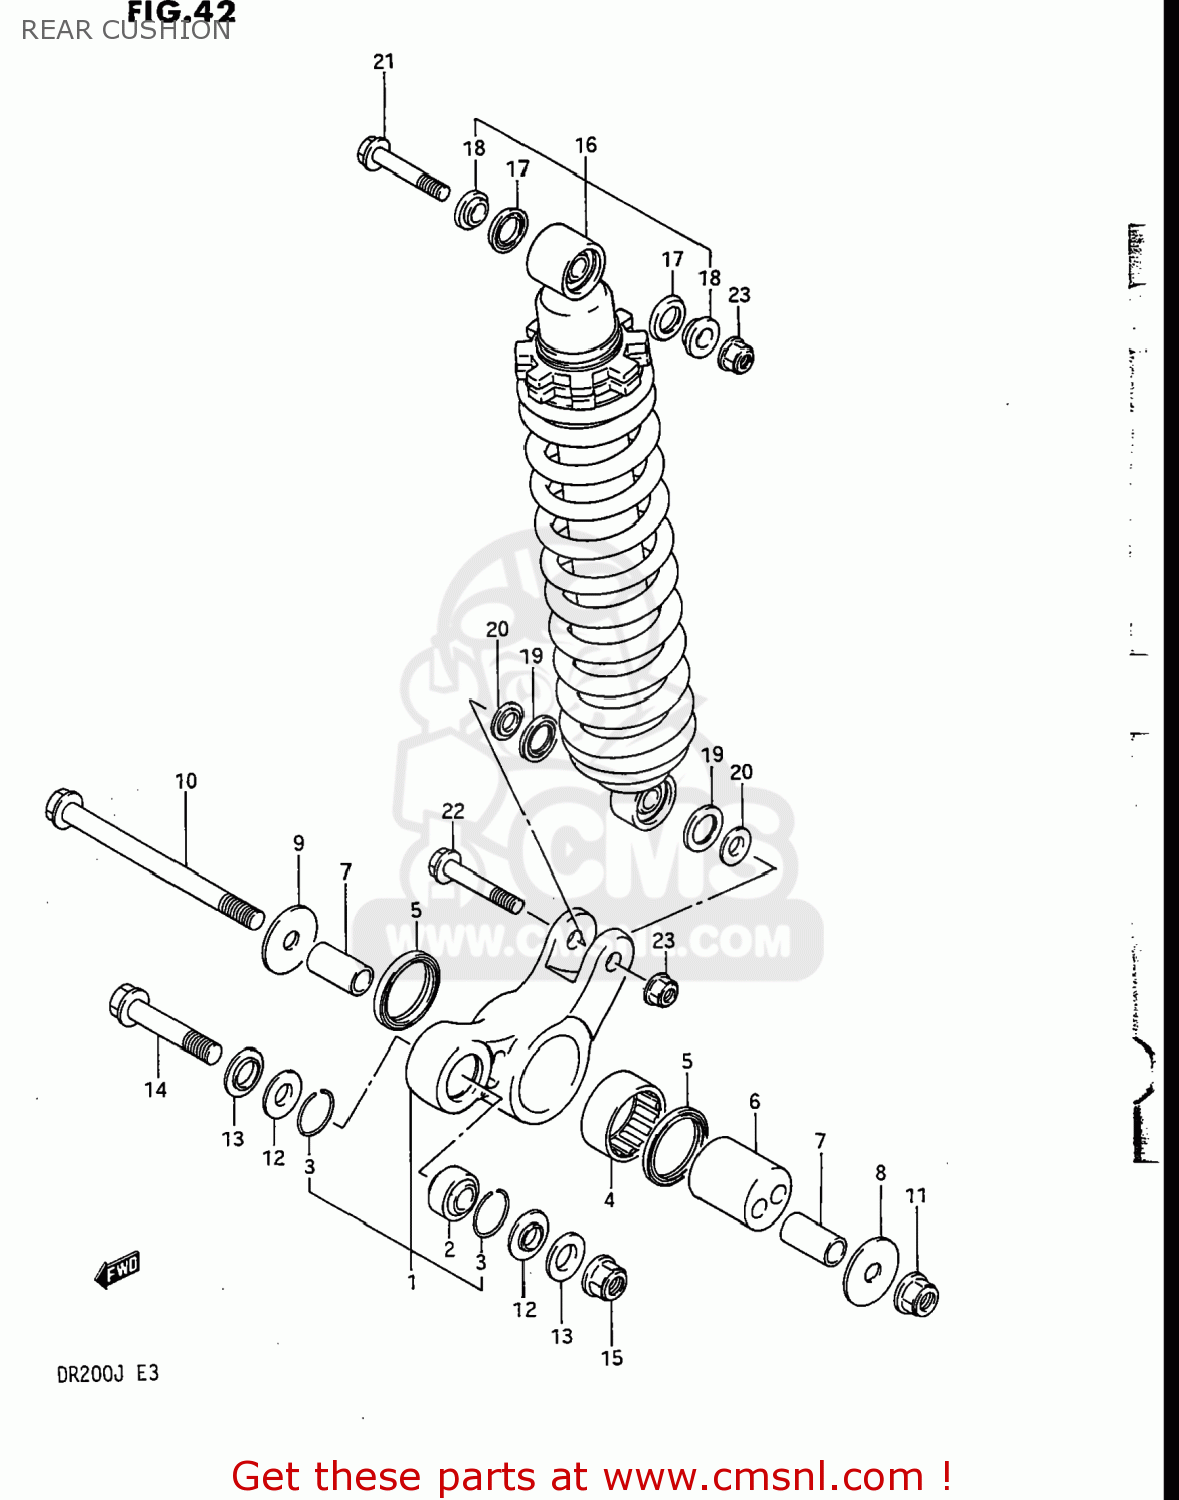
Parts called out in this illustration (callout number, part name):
1	LEVER SET,RR CUSHION
2	BEARING(12X26X16)
3	RING,STOPPER
4	BEARING(37X47X20)
5	SEAL,DUST
6	SPACER,RR SUSPENSION ECCENTRIC
7	SPACER,CUSHION LEVER SHAFT
8	WASHER(12X40X3)
9	WASHER,THRUST,R
10	SHAFT,REAR CUSHION LEVER
11	NUT 12MM
12	SEAL,RR CUSHION ROD DUST
13	SPACER,RR CUSHION ROD
14	BOLT,CUSHION LEVER FR
15	NUT 12MM
16	ABSORBER ASSEMBLY,REAR SHOCK
17	DUST SEAL
18	SPACER
19	SEAL,DUST
20	COLLAR
21	BOLT,REAR SHOCK ABSORBER
22	BOLT(10X48)
23	NUT
